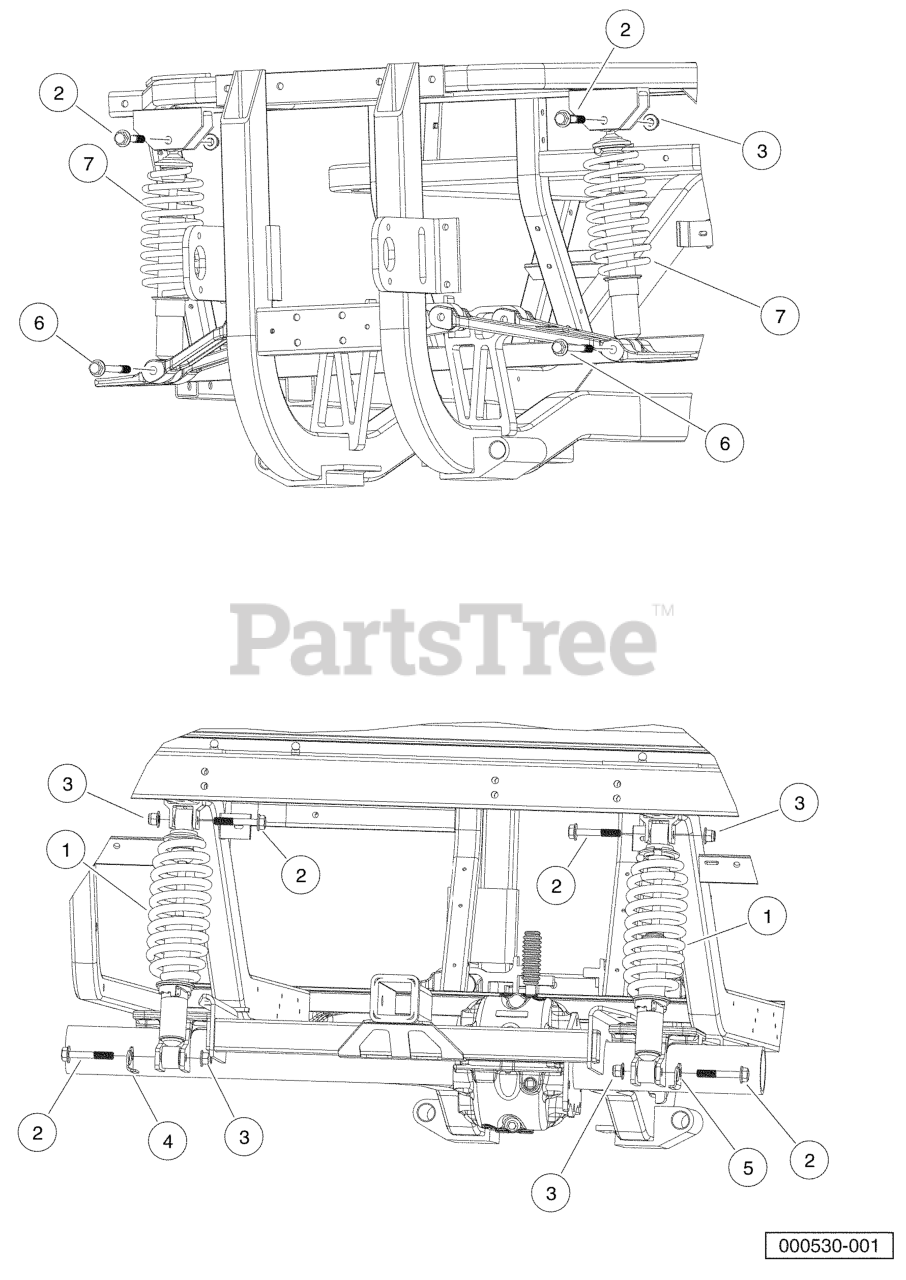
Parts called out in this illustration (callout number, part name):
1	SHOCK, COIL OVER REAR
2	BOLT, FLG, M12X1.75X70
3	NUT FLG, M12X1.75, NYLON GR 10
4	BRKT, LINE, HYD, SHK MNT, DRV
5	BRKT, LINE, HYD, SHK MNT, PASS
6	BOLT FLG, M12X1.75X100, PATCH
7	ASM, COIL & SHOCK, FRT
